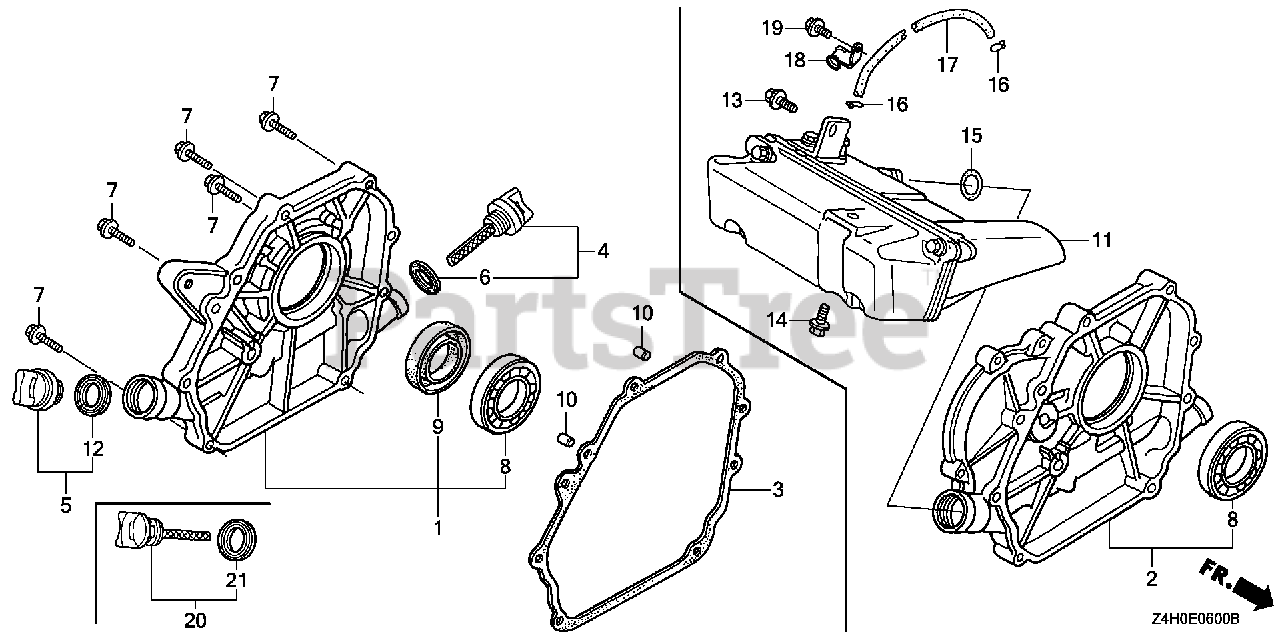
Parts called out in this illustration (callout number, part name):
1	COVER ASSY., CRANKCASE
3	GASKET, CASE COVER
4	CAP ASSY., OIL FILLER
5	CAP ASSY., OIL FILLER
6	GASKET, OIL FILLER CAP
7	BOLT, FLANGE (6X28) (CT200) Use up to Engine SN 1530314.
8	BEARING, RADIAL BALL (62/22)
9	OIL SEAL (22X41X6)
10	PIN A, DOWEL (8X14)
12	GASKET, OIL FILLER CAP
